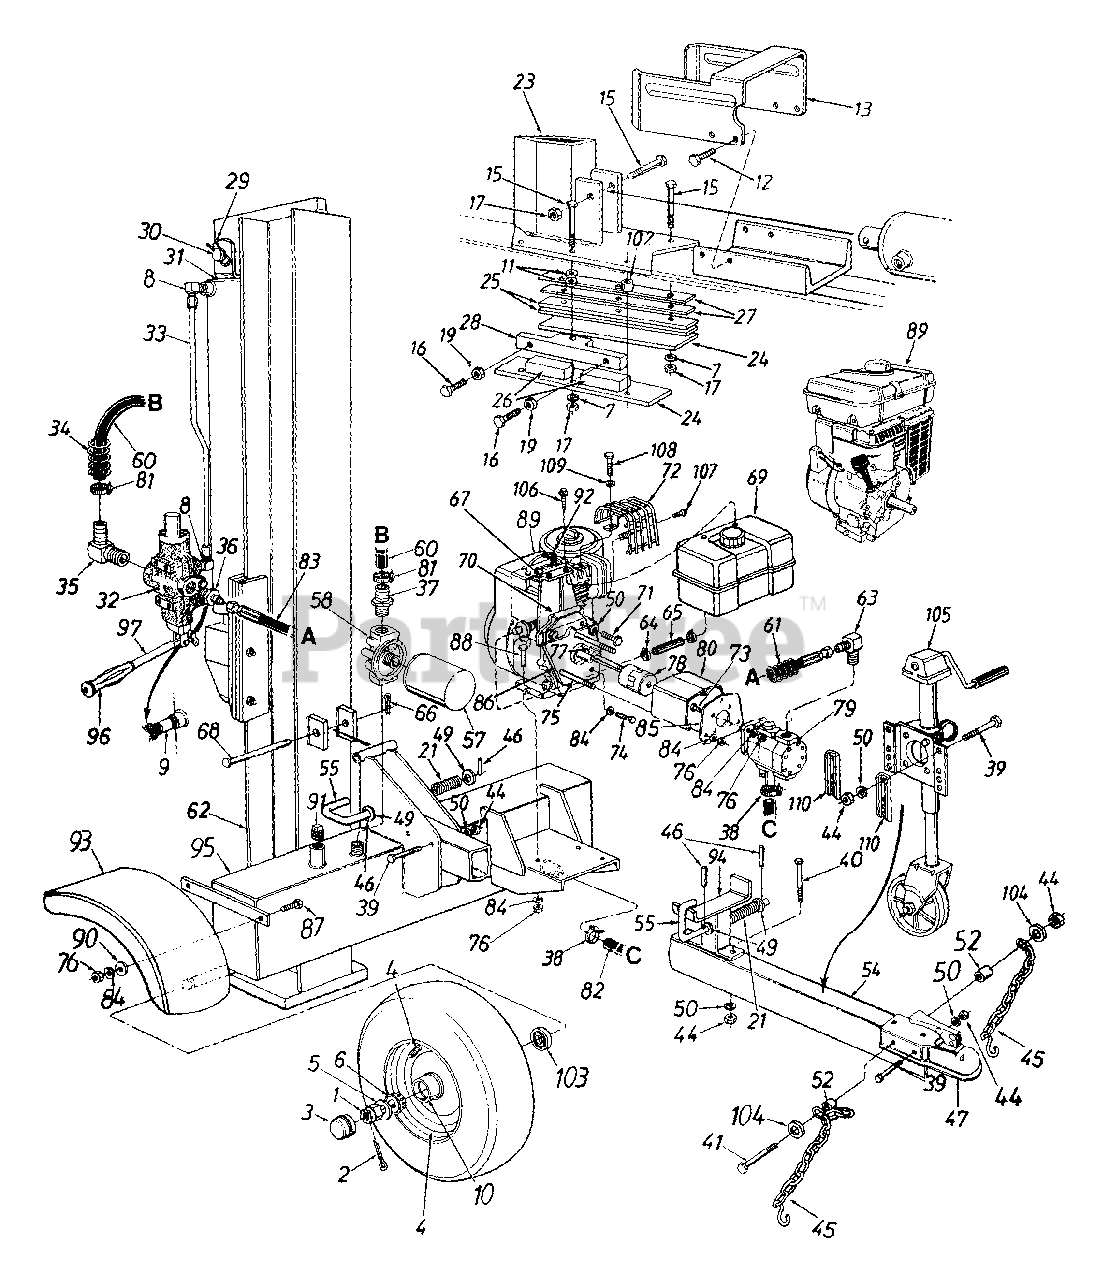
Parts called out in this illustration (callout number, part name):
1	Slotted Nut 3/4-16 Thd.
2	Cotter Pin 5/32" Dia.
3	Hub Cap
4	Wheel Ass'y. Comp.
4	Tire Only
4	Rim Only
4	Air Valve Only
5	Fl-Wash. .76" I.D. x 1.5" O.D.
6	Bearing Cone
7	L-Wash. 1/2" I.D.
8	90ø Solid Male Adapter
9	Pipe Nipple 1/2 NPT
10	Bearing Cup
11	Fl-Wash. .531" I.D. x .94" O.D.
12	Hex Cap Scr. 3/8-16 x 1" Lg.
15	Hex Bolt 1/2-20 x 2.75" Lg. (Grade 8)
16	Hex Bolt 3/8-24 x 1.5" Lg.
17	Hex L-Nut 1/2-20 Thd.
19	Hex Jam Nut 3/8-24 Thd. (Grade 5)
21	Comp. Spring 4" Lg.
23	Wedge Ass'y.
27	Adjustable Gib Shim
29	External Cotter Pin
30	Cylinder Mounting Pin
33	Metal Pressure Tube
34	Hose Guard
35	Return Elbow
36	Adapter
37	3/4" Hose Barb.
38	Hose Clamp 1.5" O.D.
39	Hex Bolt 3/8-16 x 3" Lg. (Grade 8)
40	Hex Bolt 3/8-16 x 4.75" Lg.
41	Hex Bolt 3/8-16 x 4.25" Lg.
44	Hex Nut 3/8-16 Thd.
45	Chain - Tow Hitch
46	Roll Pin
47	Hitch Coupler
49	Fl-Wash. .635" I.D. x .93" O.D.
50	L-Wash. 3/8" I.D.
52	Spacer .445" Lg.
57	Filter Element
58	Filter Head
60	Return Hose 3/4" I.D. x 44" Lg.
61	Hose Guard
64	Hose Clamp .37" Dia.
65	Fuel Line 6" Lg.
66	Cotter Pin 1/8" Dia.
67	Tank Mtg. Brkt.
68	Hinge Pin 1/2 x 4.8" Lg.
69	Fuel Tank Ass'y.
70	Support Brkt.
71	Hex Bolt 3/8-16 x 1" Lg.
72	Muffler Guard
73	Hex Bolt 5/16-24 x 1" Lg.
74	Hex Bolt 5/16-24 x .62" Lg.
75	Hex Bolt 5/16-24 x 5.25" Lg.
75	Hex Bolt 5/16-24 x 5" Lg.
76	Hex Nut 5/16-24 Thd.
77	Sq.-Key 1/4" x 2" Lg.
77	Sq.-Key 3/16 x .75" Lg.
78	Flexible Coupling
79	Gear Pump
80	Coupling Shield
81	Hose Clamp 5/8"
82	Suction Hose 1" I.D.
83	High Pressure Hydraulic Hose 48"
84	L-Wash. 5/16" I.D.
85	Rear Coupling Support Brkt.
86	Front Coupling Support Brkt.
87	Hex Bolt 5/16-24 x .75" Lg.
88	Hex Bolt 5/16-24 x 1.75" Lg.
89	Engine
90	Fl-Wash. .344" I.D. x .875" O.D.
91	L-Vent Pipe Plug
92	Spark Plug Boot
97	Control Handle
102	Spacer 1/2" I.D. x .86" Lg.
103	Bearing Seal Only
104	Fl-Wash. 3/8" I.D. x .87" O.D.
105	Jack Stand
106	Hex AB-Tap Scr. 1/4 x 3/4" Lg.
107	Hex Wash. Hd. Scr. #8 x .5" Lg.
108	Hex Bolt 1/4-20 x .5" Lg.
109	Fl-Wash. .25" I.D. x .5" O.D.
